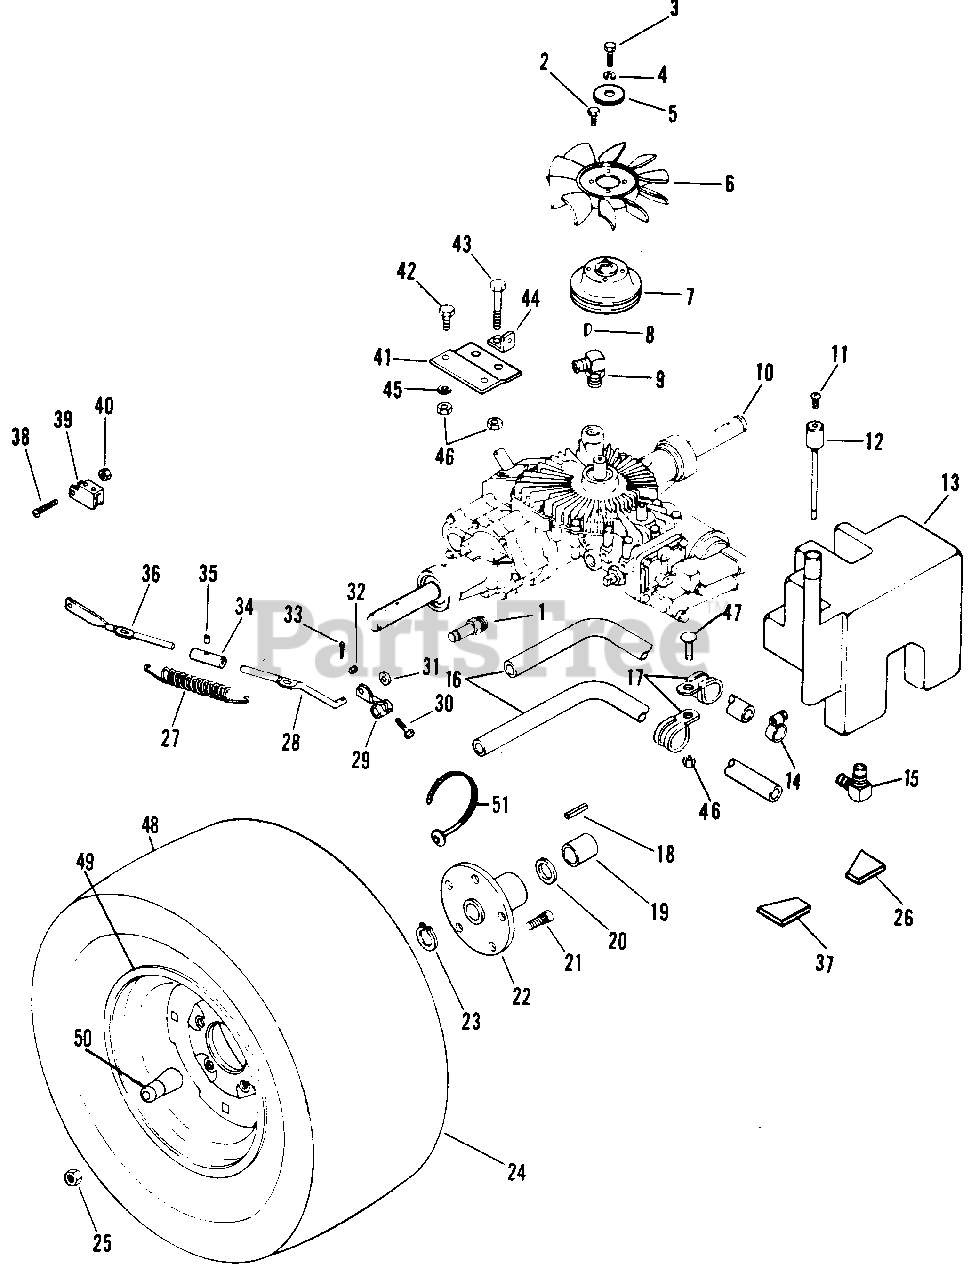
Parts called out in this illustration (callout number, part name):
1	Adapter, #4604-10-10
2	Screw, Mach. 10-24 x .50 PHD
3	Bolt, Hex 1/4-20 x .750
4	Washer, Lock 1/4 Reg.
5	Washer, Special
6	Fan
7	Pulley, Transaxle
8	Key, Woodruff .187 x .625 Hrd. #61
9	Fitting
10	Transaxle
11	Screw, Vent
12	Dipstick
13	Tank, Hydraulic
14	Clamp, .88 DIA. Hose
15	Fitting, O-Ring Barb S/A
16	Hose, Hydraulic
17	Clamp, Steel 1.00
18	Key, Straight
19	Bush., 1.44 x 1.01 x 1.92 Stl.
20	Race, Bearing Thrust .095
21	Lug Bolt
22	Hub, Wheel
23	Snap Ring
24	Asm., Wheel 23 x 8.50-12
25	Nut, Lug 7/16-20
26	Pad, Tank L.H.
27	Spring, Extension
28	Front Dump Valve Rod
29	Dump Valve Arm
30	Bolt, Hex 1/4-20 x 1.00
31	Washer, Flat .406 x .812 x .065
32	Nut, Lock 1/4-20
33	Pin, Cotter .094 x .75
34	Collar
35	Pin, Roll .125 x .625
36	Rear Dump Valve Rod
37	Pad, Tank R.H.
38	Screw, Mach. 10-24 x 1.0 PHCR
39	Latch
40	Nut, Lock 10-24
41	Bracket, Transaxle Mounting
42	Bolt, Hex 3/8-16 x .875
43	Bolt, Hex 3/8-16 x 3.25
44	Spring Anchor
45	Washer, Flat .375 x 1.125 x .065
46	Nut, Lock 3/8-16
47	Bolt, 3/8-16 x 1.00 Rd Hd Sq Nk
48	Tire, Rear 23 x 8.50-12
49	Weldment, Rim Rear
50	Assembly, Valve Stem
51	Clamp, Universal
